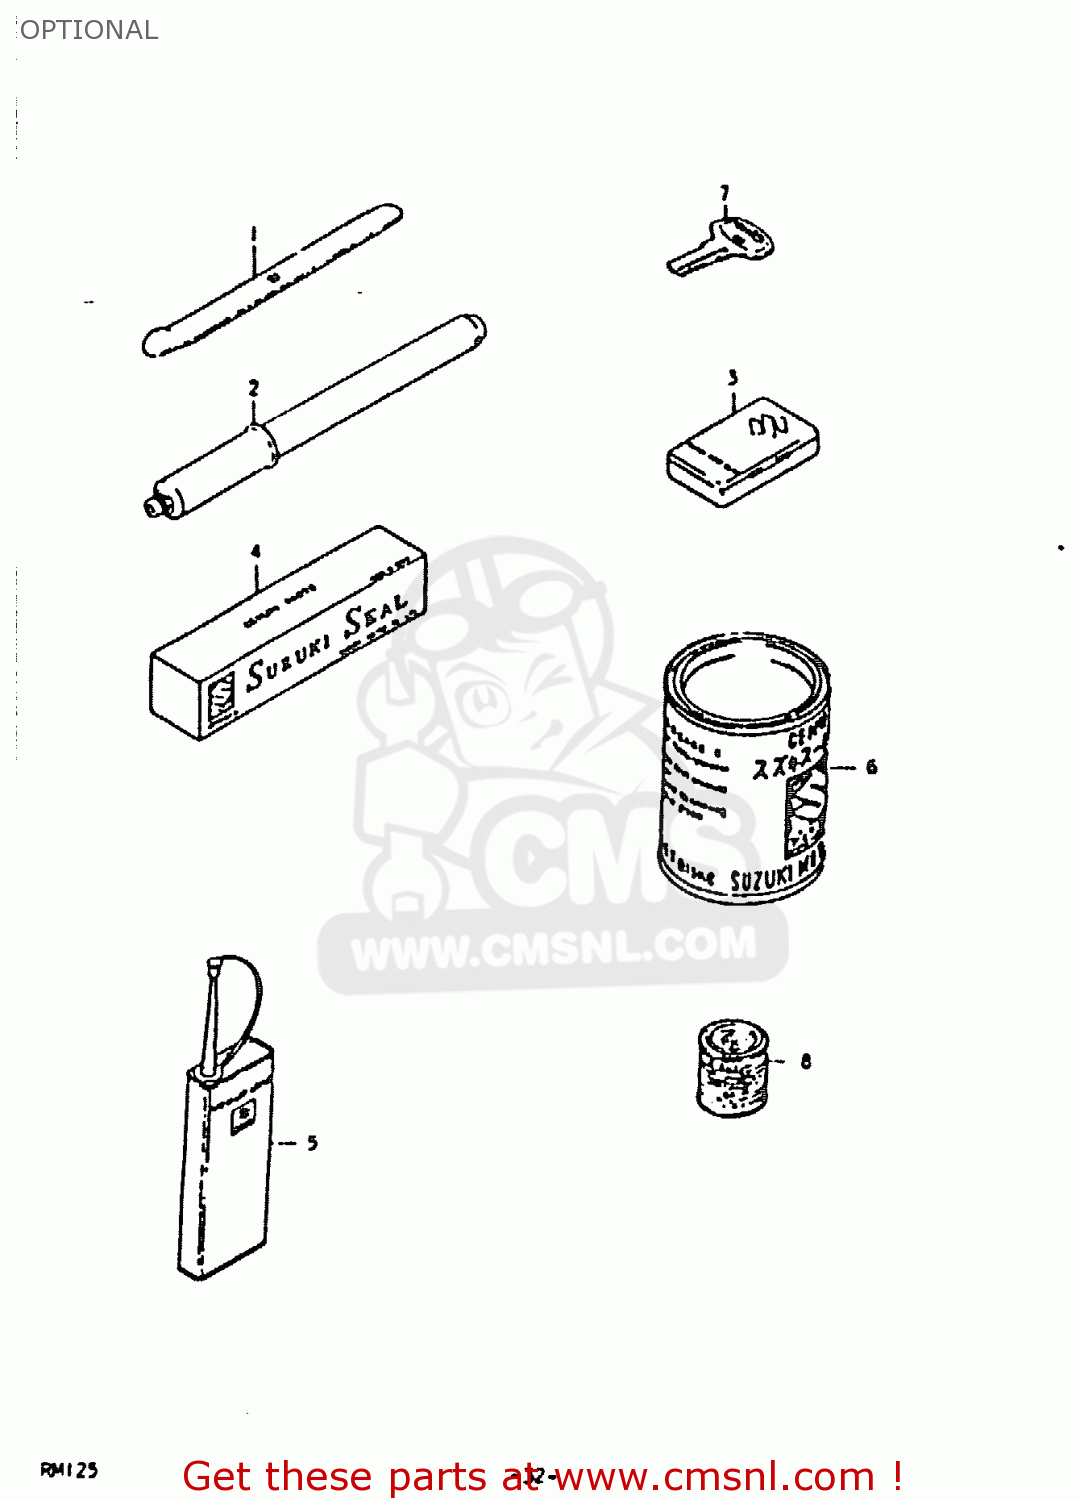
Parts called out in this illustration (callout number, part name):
1	LEVER,TIRE
2	INFLATOR, AIR
3	TUBE REPARING TOOL
4	BOND 1104
5	THREAD LOCK NO.1401 CLEAR 200G
6	GREASE(C)EP2 LITHIUM 150G
8	PAINT,BLACK
9	PAINT (BLACK)
